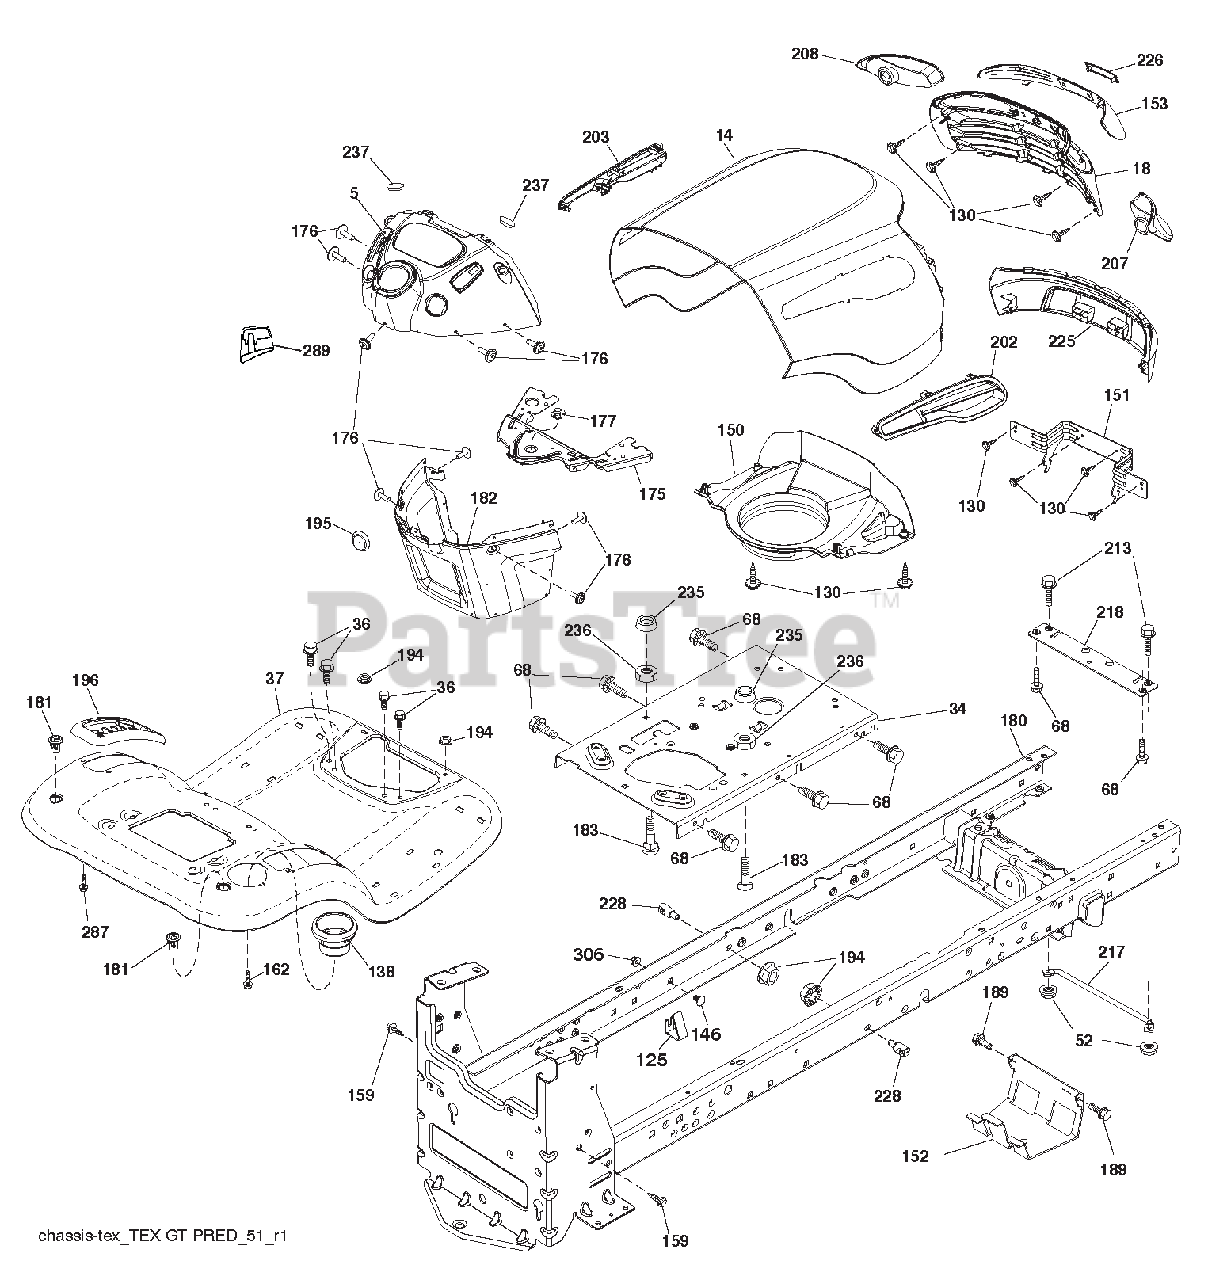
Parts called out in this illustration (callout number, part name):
5	DASH P/L TEX CABLE
18	GRILLE.ELITE.ARIENS.BLACK
34	PLATE.ENGINE.WELDED.CHASSIS
36	SCREW.5/16-18X3/4.SMGML.TAP/R
37	FENDER TLT W/CPH W/FW 422
52	Nut, Hex, Crownlock 5/16-18
68	SCREW.THDROL.5/16-18 X 1/2TYTT
125	CLIP.FUEL.LINE
138	CUPHOLDER TL TEX 428
150	AIR DUCT
151	BRACKET.PIVOT
152	SHIELD.BROWNING.W/TEX
153	LENS.BAR
159	SCREW.HEXWSH THDR3/8-16X3/4.BL
162	SCREW.HEX.WSH.HI-LO.1/4X1/2UNC
175	CROSSMEMBER.LT
176	SCREW.#10-24X5/8.RND.QUDRX.GIM
177	BUSHING.STEERING.YT/GT
180	CHASS WLDMT TL 12 GA/2PC 18/22
181	BUSHING MNT FEND CRGO BLK TEX
182	DASH.LOWER.LT.CCS
183	BOLT.FIN.HEX.5/16-18 UNC X1-1/
189	SCREW.5/16-18X3/4.SMGML.TAP/BL
194	Nut, Lock Hex Flange 5/16-18 u
195	PLUG HOLE DASH TOWER
196	CONSLE.ASM.DECK.LFT.BL/RBT.TLT
202	VENT.RH
203	VENT.LH
207	BEZEL.RH
208	BEZEL.LH
213	Bolt, Hex Head 5/16-18 x 3/4
217	ROD.PIVOT.HOOD
218	X-PIECE.HOOD.STOP.NON/STEALTH
226	ARIENS.LOGO.PLATE
228	STUD.FASTNER.W/'D'ANTI-ROTATIO
235	SPACER.FENDER
236	NUT.CENTER LOCK.5/16-18 UNC
237	PLUG.MOUNT.CARGO
287	SCREW.HEX.WASHEAD.1/4-20 X 3/8
289	PLUG.CRUISE.CONTROL
306	Nut, Hex, Flangelock 3/8-16
